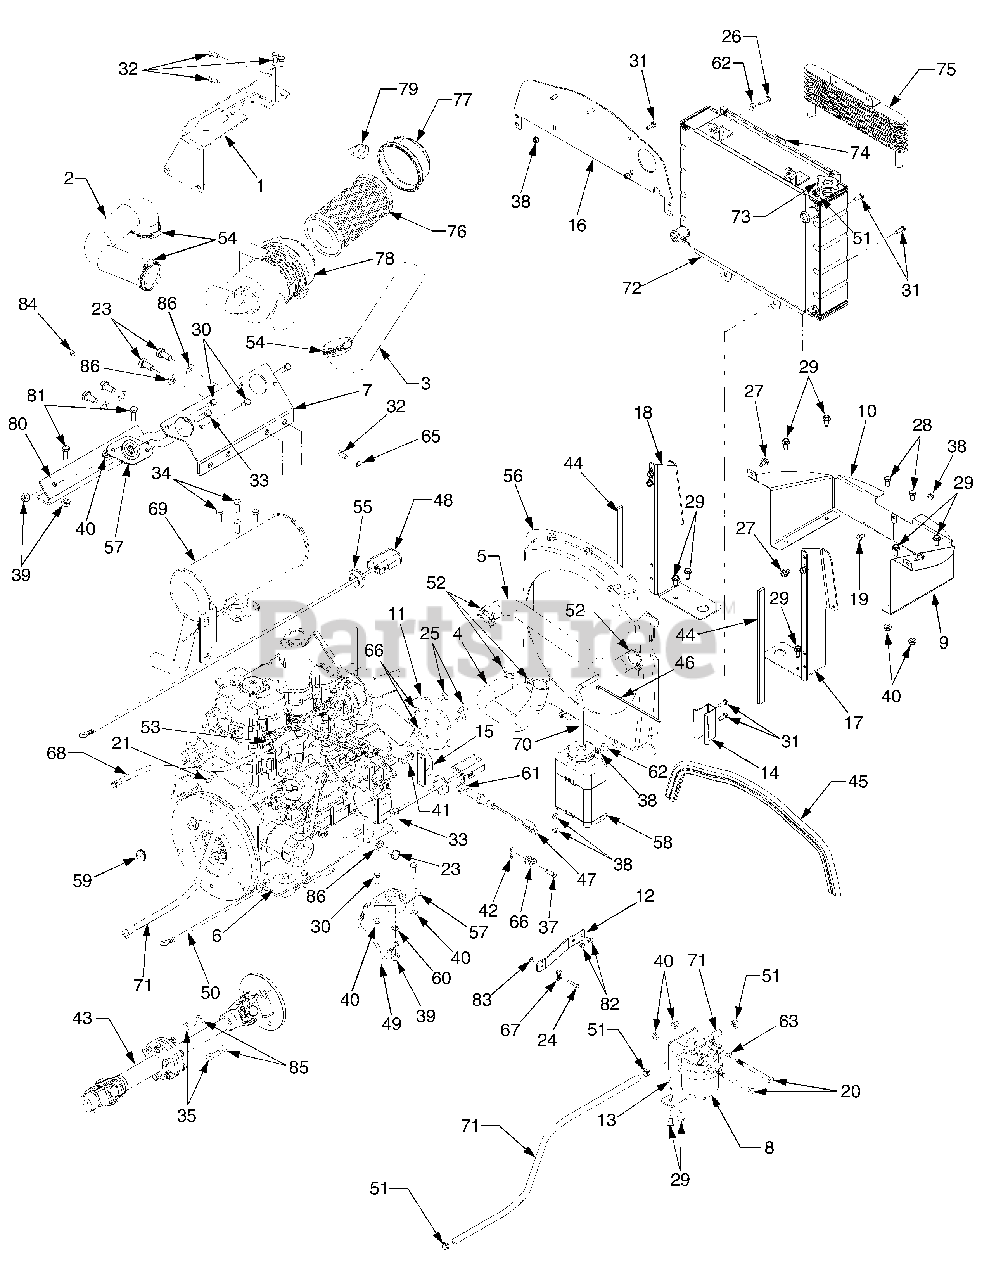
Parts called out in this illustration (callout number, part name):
1	Bracket, Air Filter Mtg.
2	Hose, Air Inlet
3	Hose, Air Filter
4	Hose, Radiator to Engine
5	Hose, Engine to Radiator
6	Bracket, Engine RH
7	Bracket, Engine LH
8	Filter Assembly, Fuel
9	Plate, Baffle RH
10	Plate, Baffle, LH
11	Plate, Engine RPM
12	Bracket, Cable Mtg.
15	Bracket, Sensor Mtg.
16	Plate, Radiator Baffle
17	Bracket, Radiator Support RH
18	Bracket, Radiator Support LH
19	Screw, Hex Cap, 1/4-20 x .5 Gr5
20	Screw, Hex Cap, 5/16-18 x 4.0 GR5
21	Screw, Hex Wash Hd Tapp 10-16 x .5
23	Screw, Hex Cap, M12-1.25 x 25 GR8.8
24	Screw, Mach. #10-24 x 1.0 GR5
25	Screw, Countersink Torx Hd M8-1.25 x 20
26	Screw, Hex Cap 1/4-20 x 1.0 GR5
27	Screw, Hex Wash Hd Tapp 5/16-18 x .5
28	Screw, Hex Wash Hd Tapp 3/8-16 x .75
29	Screw, Hex Wash Hd Tapp 5/16-18 x .75
30	Screw, Hex Cap 5/16-18 x .75 GR5
31	Screw, Hex Cap 1/4-20 x .75 GR5
32	Screw, Hex Cap, M8-1.25 x 16
33	Screw, Hex Cap 3/8-16 x 2/0 GR5
34	Screw, Hex Cap, M8-1.25 x 25 GR8.8
35	Screw, Hex Cap, M10-1.5 x 25 GR5
37	Pin, Clevis, .312 x 1.0
38	Nut, Hex Inesrt Flange Lock, 1/4-20 GrF
39	Nut, Hex Flange Insert Lock, 3/8-16 GrF
40	Nut, Hex Flange Lock, 5/16-18 GrF
41	Nut, Jam, 5/8-18 GR5
42	Pin, Internal Cotter
43	Shaft, Drive
44	Tape, Foam, .625 wide
45	Seal, Heat Baffle
46	Tie, Cable
47	Sensor, RPM
48	Wire, Battery Pos.
49	Wire, Ground
50	Wire, Battery Neg.
51	Clamp, Hose
52	Clamp, Hose
53	Clamp, Hose
54	Clamp, Adjustable Hose
55	Grommet, Hose Guard
56	Shroud, Fan
57	Mount, Compression Engine
58	Container, Over Flow
59	Grommet, Rubber
60	Washer, External Lock, 3/8
61	Washer, Lock, 5/8
62	Washer, Flat, .28 x .74 x .063 .
63	Washer, Flat, .344 x .688 x .065
65	Washer, External Lock, 5/16 ...
66	Washer, Flat, .344 x .75 x .12 .
67	Clamp, Casing
68	Hose, Fuel Line Return
69	Muffler, Engine
70	Hose, Over Flow
71	Fuel Line, 5/16 ID
73	Cap, Radiator, 13psi
74	Screen, Debris
75	Cooler, Oil
76	Element, Air Cleaner
77	Cap, Air Cleaner
78	Canister, Air Cleaner
79	Nozzle, Air Cleaner
80	Bracket, Engine Mtg.
81	Screw, Hex Cap, 3/8-16 x 1.0 GR5
82	Screw, Hex Cap, M6-1.0 x 10mm GR8.8
83	Nut, Hex Insert Lock, #10-24 ..
84	Nut, Flange Lock, M6-1.0
85	Washer, Flat, .375 x .738 x .063
86	Washer, Flat, .535 x .93 x .09 .
